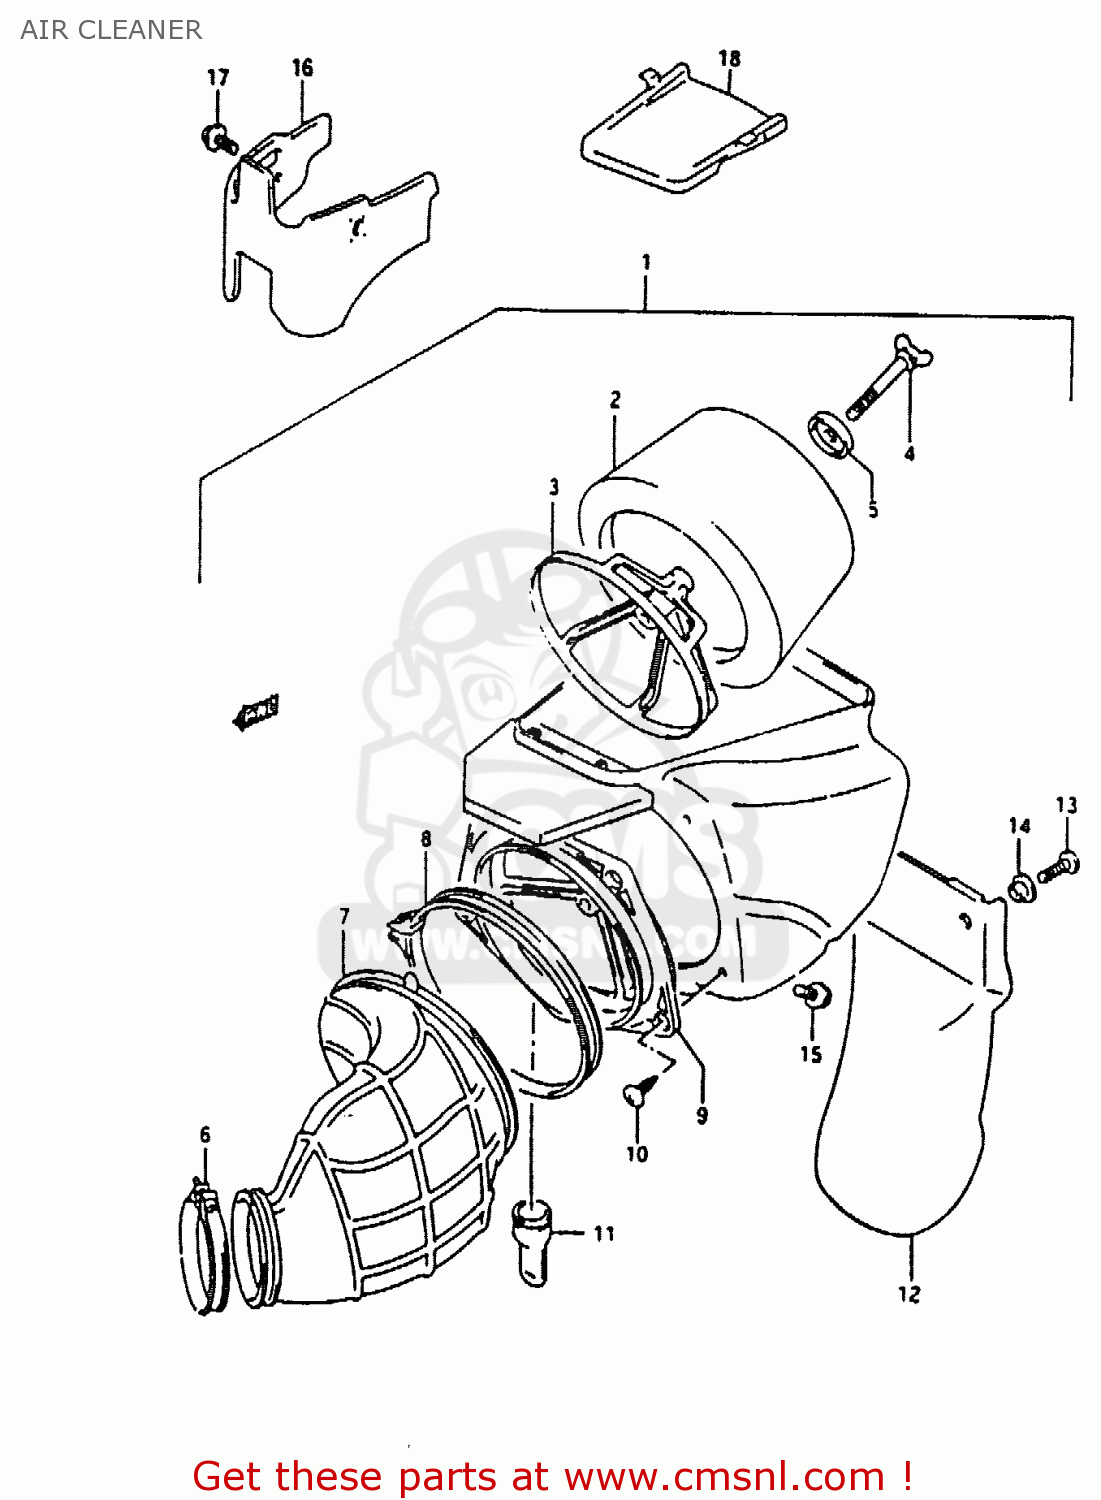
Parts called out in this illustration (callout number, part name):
1	CLEANER ASSEMBLY,AIR
2	FILTER
3	HOLDER,FILTER
4	BOLT,WING
5	WASHER,AIR CLEANER
6	CLAMP
7	TUBE,OUTLET
8	CLAMP
9	BASE,FILTER
10	SCREW
11	CAP,DRAIN
12	GUARD,MUD
13	SCREW
14	COLLAR
15	BOLT
16	GUARD,MUD
17	SCREW(6X12)
18	CAP,AIR CLEANER
